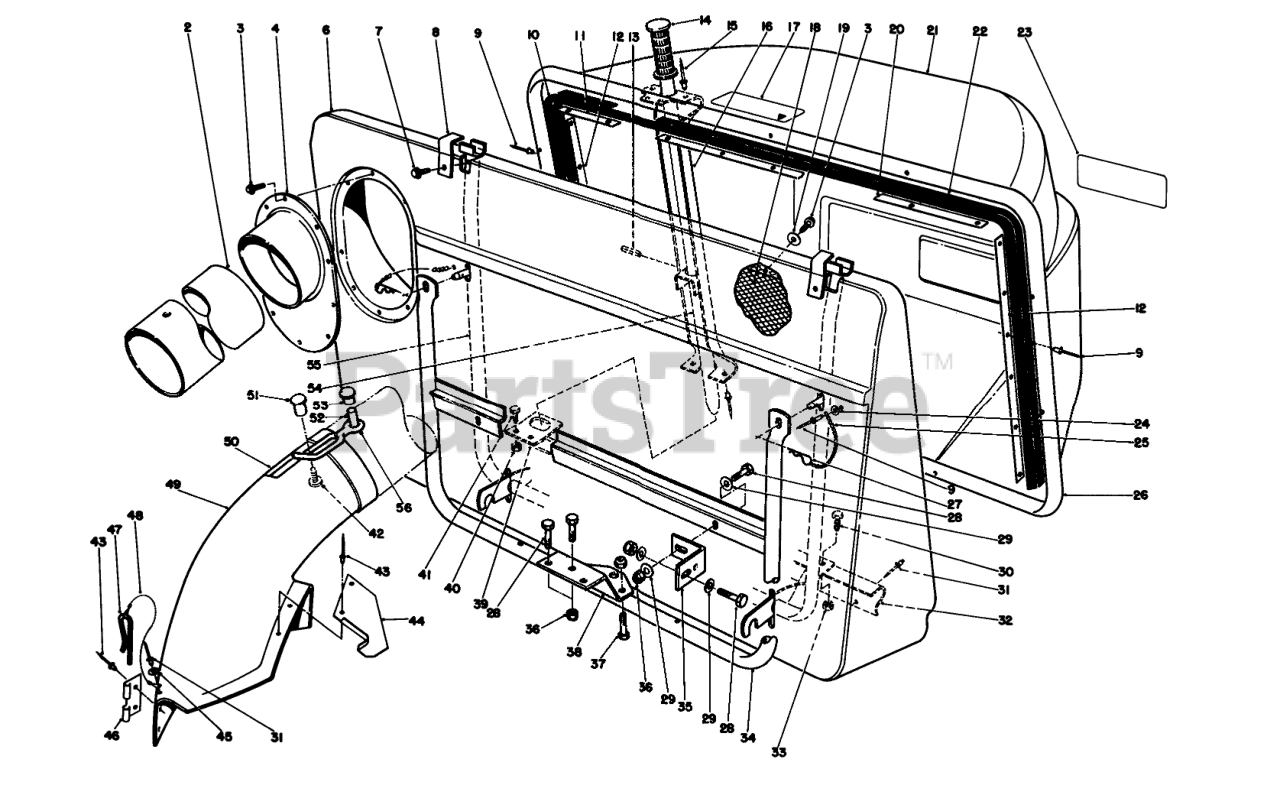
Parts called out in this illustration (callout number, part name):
2	Duct
3	SCREW-HWHTF
4	DUCT ADAPTER
6	Bag Front
7	SCREW-HWH
8	RETNR PIVOT BRKT
10	RH BAG SEAL
11	RETNR TOP EXT.
12	BAG RETNR EXT.
13	PIN-ROLL
15	RIVET-POP
16	DUMP HDLE CHANL WA
17	Decal Warning
18	Screen Bag
19	WASHER-FLAT
20	EXTRUSION BAG RETAINER
21	REAR GRASS BASKET
23	EASY EMPTY BAG DECAL
24	WASHER
25	10 LINK CHAIN W/O HOOK
26	BAG SUPT ASM FRM
27	PIN-HAIR
28	SCREW-HH
29	WASHER-PLAIN
30	SCREW-HH
31	RIVET-BLIND
32	FRAME SUPT BRKT B
33	NUT-LOCK, CONE
34	BAG SUPPORT WA
35	MTG BRACKET
36	NUT-LOCK, NI
37	SCREW-HH
38	MTG PLATE B
39	Hanger-Frame Lower
40	NUT-LOCK, CONE
41	SCREW-HH
42	Screw
43	RIVET-BLIND
44	CHUTE SUPT BRKT
45	WASHER-PLAIN
46	BRACKET-MOUNTING, CHUTE
47	PIN-LOCKING, CHUTE
48	LANYARD
49	Assembly-Chute (Incl. Ref. #31, & 41-50)
50	DECAL-DANGER
52	SPACER-INTERLOCK
53	FASTENER-PANEL
54	DUMP HANDLE ASM
55	Bag Frame
56	RETAINER-DUCT
